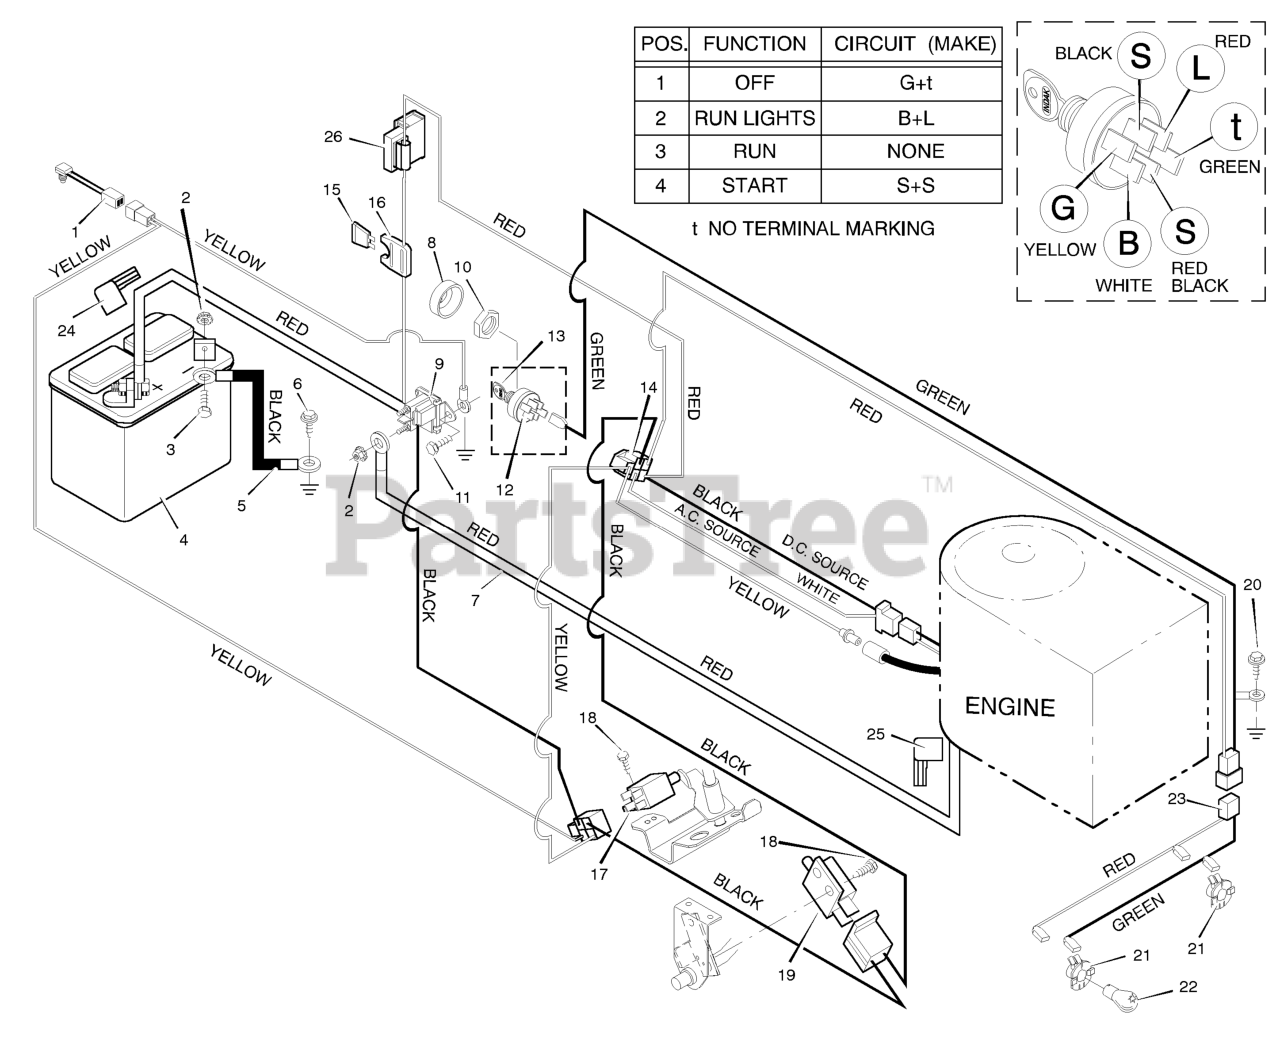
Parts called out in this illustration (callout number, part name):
1	Switch, Seat Sensor
2	Locknut
3	Bolt, Hex
4	Battery
5	Cable, Battery Ground
7	Cable, Red Battery
8	Cap, Ignition
9	Solenoid
10	Nut
12	Switch,Ignition
13	Key, Ignition
14	Harness, Chassis Wire
16	Holder, Fuse
17	Switch, Clutch
19	Switch, Clutch
20	Screw
21	Socket, Light
22	Bulb, Light
23	Harness, Light Wire
24	Cover, Terminal
25	Cover,
26	Ammeter
